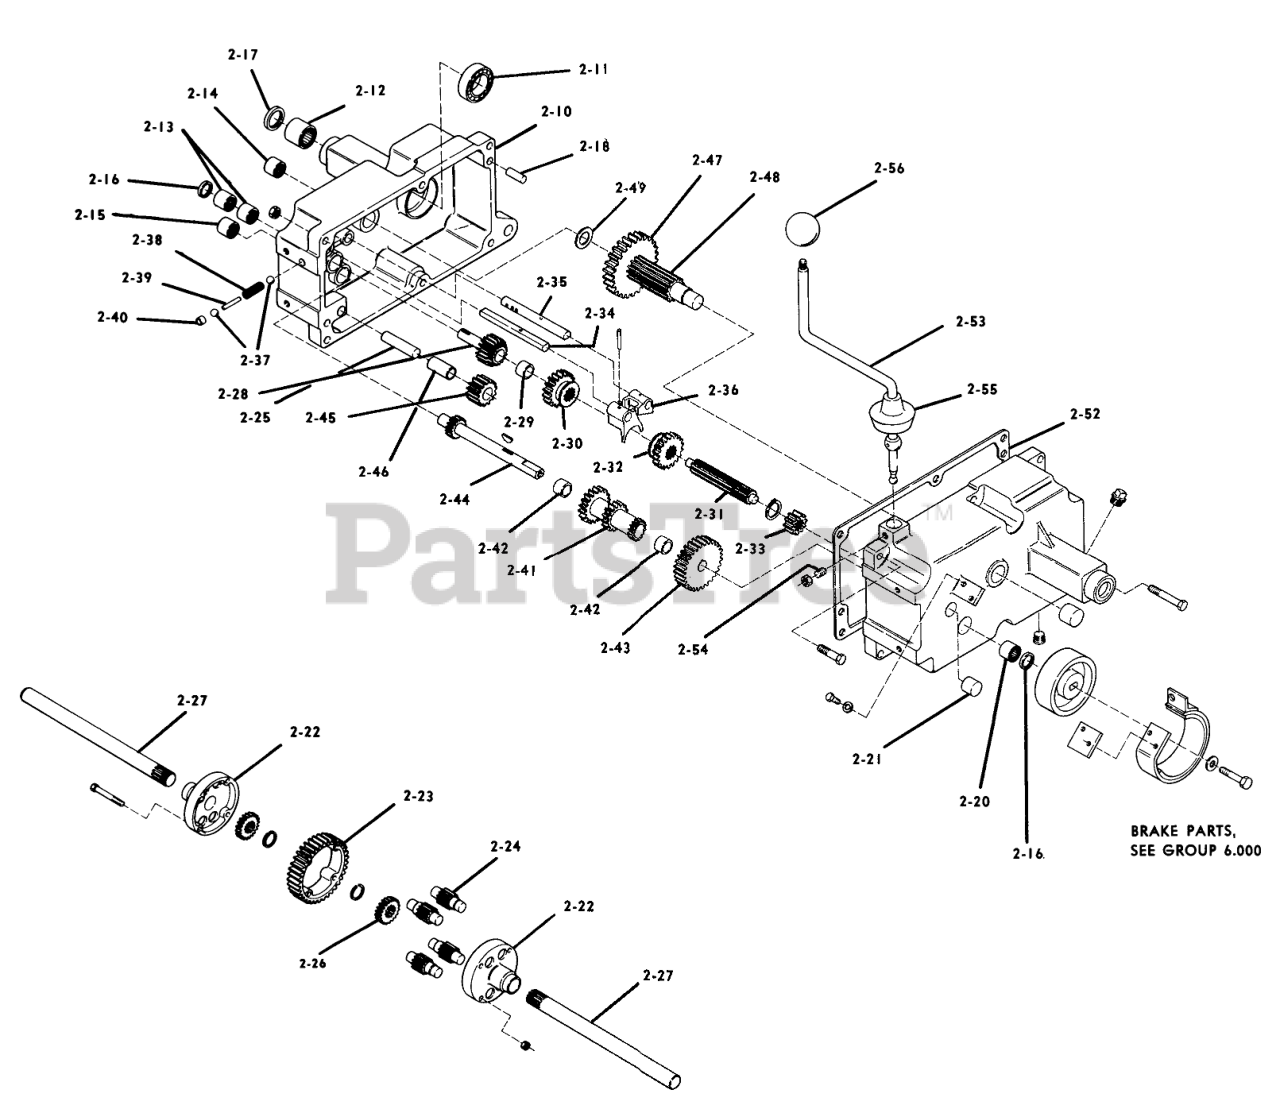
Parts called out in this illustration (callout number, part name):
2-10	Case R.H
2-11	BALL BRG 1 1/2 I.D.
2-12	BEARING-NEEDLE
2-13	NEEDLE BEARING
2-14	BEARING-NEEDLE
2-15	BEARING-NEEDLE
2-16	SEAL-OIL
2-17	OIL SEAL
2-18	PIN-DOWEL
2-20	BEARING-NEEDLE
2-21	Bearing Needle
2-22	Differential Case
2-23	DIFFERENTIAL BULL GR
2-24	GEAR-PINION, 11T
2-25	PIN-DIFFERENTIAL
2-26	AXLE GEAR
2-28	INPUT SHAFT
2-29	BEARING-NEEDLE
2-30	GEAR
2-31	Shaft Spline
2-32	GEAR
2-33	GEAR
2-34	RAIL-SHIFT
2-35	RAIL-REAR SHIFT
2-36	FORK-SHIFT
2-37	BALL-DETENT
2-38	Spring
2-39	PIN-SHIFT
2-40	CUP-PLUG
2-41	Cluster Gear
2-42	BUSHING-BRONZE
2-43	GEAR-CLUSTER SHAFT
2-44	Cluster Shaft
2-45	GEAR/BUSHING ASM-REVERSE IDLER
2-46	BUSHING
2-48	PINION SHAFT
2-49	WASHER-THRUST
2-52	GASKET-TRANSMISSION
2-53	Shift Stick
2-54	SETSCREW
2-55	COVER-DUST
2-56	SHIFT KNOB
